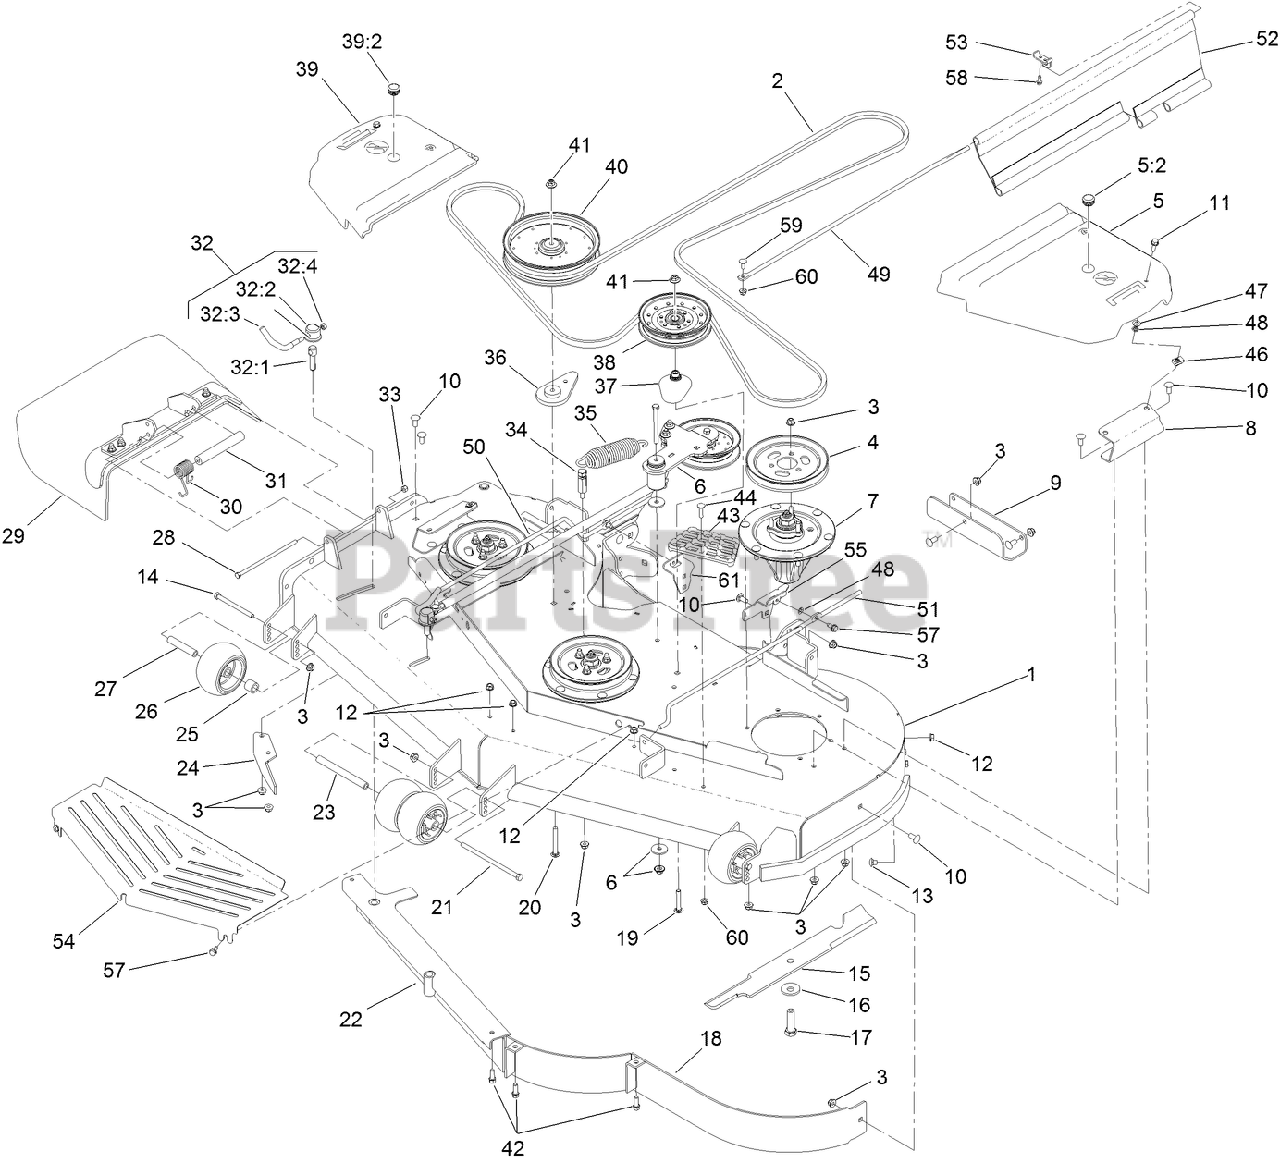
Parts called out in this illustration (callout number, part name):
1	DECK DECAL ASM
2	BELT-V
3	NUT-HF, NI
4	Pulley
5	LH BELT COVER ASM
5:2	PLUG-PLASTIC
6	IDLER ARM ASM
7	SPINDLE ASM
8	BRACKET-COVER, BELT
9	PLATE-SKID
10	SCREW-CARR
11	SCREW-HHF
12	NUT-HHF, WHIZ
13	SCREW-CARR
14	SCREW-HH
15	BLADE-HI FLOW
16	Washer-Blade Bolt, Heavy
17	SCREW-BLADE
19	BOLT-CARR, SHORT NECK
20	SCREW-CARR
21	SCREW-HH
22	BAFFLE ASM
23	SPACER-WHEEL
24	BAFFLE-DISCHARGE
25	TUBE-SPACER
26	ROLLER-SCALP, ANTI
27	TUBE-SPANNER
28	SCREW-HH
29	RUBBER DEFLECTOR ASM
30	SPRING-TORSION
31	SPACER
32	LEVER ASM
32:1	Screw-Lock
32:2	CAP-LOCK
32:3	Lever-Lock
32:4	NUT-LOCK, NI
33	NUT-LOCK, NI
34	ANCHOR-SPRING, TALL
35	SPRING-EXTENSION
36	SPACER-IDLER
37	SPACER-PULLEY
38	PULLEY-IDLER, FLAT
39	RH BELT COVER ASM
39:2	PLUG-PLASTIC
40	PULLEY-IDLER
41	NUT-FLANGE, NI
42	SCREW-HWH
43	STEP-DECK
44	SCREW-CARR
46	NUT-U
47	WASHER-THRUST
48	NUT-PUSH
49	ROD-SUPPORT, UPPER
50	ROD SUPPORT, RH LOWER
51	ROD SUPPORT, LH LOWER
52	GUARD SIDE
53	BRACKET-MOUNTING, UPPER
54	SHIELD-FRONT
55	BRACKET-MOUNTING, REAR (LH)
57	SCREW-HWHTF
58	SCREW-HWH
59	SCREW-CARR
60	NUT-HF, NI
61	BRACKET-MOUNTING, REAR (RH)
